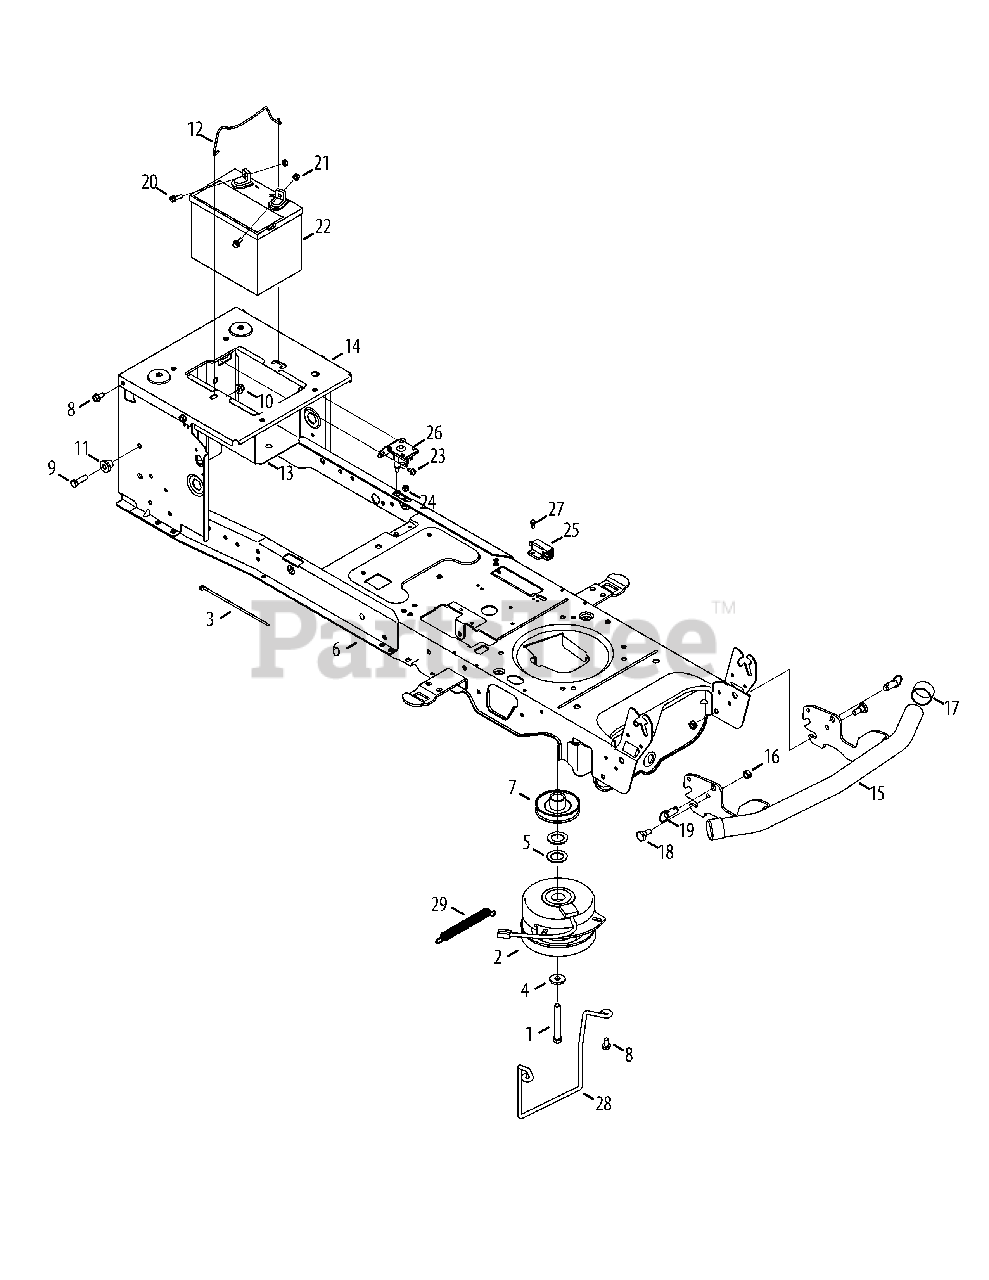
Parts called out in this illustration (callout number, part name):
1	Hex Head Screw, 7/16-20 x 3.50
2	Electric PTO Clutch
2	Clutch Wire Jumper
3	Cable Tie, 3/16 x .05 x 7.4
4	Washer, Flat, .450 x 1.25 x .164
5	Flat Washer, 1.031 x 1.620 x .095
7	Electric PTO Engine Pulley
8	Taptite Screw, 5/16-18 x .750
9	Hex Head Screw, 3/8-16 x 1.25
10	Flangelock Nut, 3/8-16
11	Shoulder Spacer, .38 x 1.0 x .70
12	Battery Holder Rod
14	Seat Frame Bracket
16	Hex Lock Nut, 3/8-16
17	Bumper Cap
18	Shoulder Bolt, .496 x .336
19	Quick Release Pin
20	Hex Head Flange, 1/4-20 x .75
21	Sems Nut, 1/4-20
23	Taptite Screw, 1/4-20 x 0.375
24	Flangelock Nut, 1/4-20
25	Interlock Switch
26	Solenoid, 12V
27	Shoulder Screw, #10-32 x .500
28	Belt Keeper Rod
29	Spr, Extn, .56 Dia X 5.52
